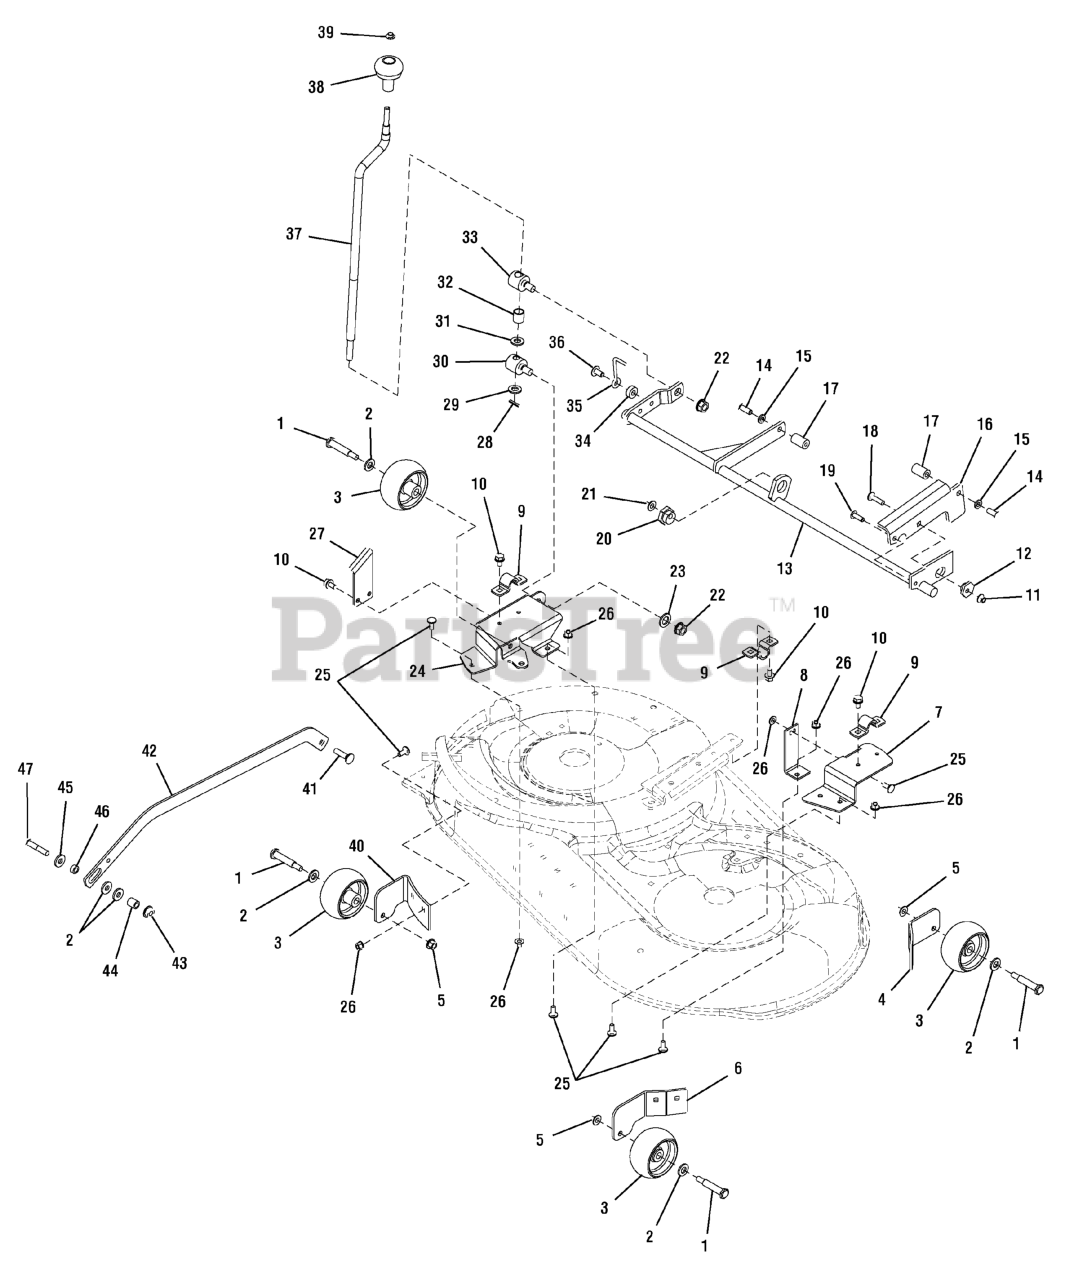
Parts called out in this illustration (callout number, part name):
1	BOLT, Wheel, 3/8-16 x 2-25/32 3/4 Thread
2	WASHER, 1/2
3	GAUGE WHEEL
4	BRACKET, Gauge Wheel LH Back
5	NUT, Hex Flange ESNA, 3/8-16
6	BRACKET, Gauge Wheel LH Front
7	BRACKET, Rear LH 42" Glass
8	BRACE, Mower 42"
9	STRAP
10	CAPSCREW, Hex Washer Head Taptite, 5/16-18 x 3/4
11	NUT, Hex Flange, 5/16-18 Collar Lock
12	CAM, Eccentric 1-1/8 A/F Hex
13	SHAFT ASSEMBLY, Rocker 42"
14	CAPSCREW, Hex Head 3/8-16 x 1, G5
15	LOCKWSHER, Spring 3/8
16	ARM, Rear Adjustment
17	SUPPORT, 1-1/4 Long
18	CARRIAGE BOLT, 5/16-18 x 1-1/4, G5
19	CAPSCREW, Hex Washer Head Taptite, 5/16-18 x 1
20	NUT, Hex Adjusting, 11/16
21	NUT, Hex Flange, 3/8-16
22	NUT, Hex Flange, Two-Way Lock, 1/2-13
23	WASHER, 5/8
24	BRACKET, Rear R.H.
25	CARRIAGE BOLT, 5/16-18 x 3/4, G5
26	NUT, Hex Flange Whiz Lock, 5/16-18
27	INDICATOR, Cut Height Upstop
28	PIN, Spring SAE 1095
29	WASHER, Detent
30	TRUNNION
31	WASHER, 1/2
32	SPACER, .66 ID
33	TRUNNION
35	STOP, Belt
36	CAPSCREW, Hex Washer Head Taptite, 3/8-16 x 1
37	CRANK, Height Adjustment
38	KNOB, Spinner
39	NUT, Push Pal, 3/8
40	SUPPORT, Gauge Wheel R.H. Front
41	BOLT, Carriage, Short Neck, 3/8-16 x 1-1/2
42	ARM, Pitch
43	NUT, Hex FlangeTwo-Way Lock, 3/8-16 GA
45	WASHER, 3/8
47	CAPSCREW, Hex Head 3/8-16 x 2, G5
